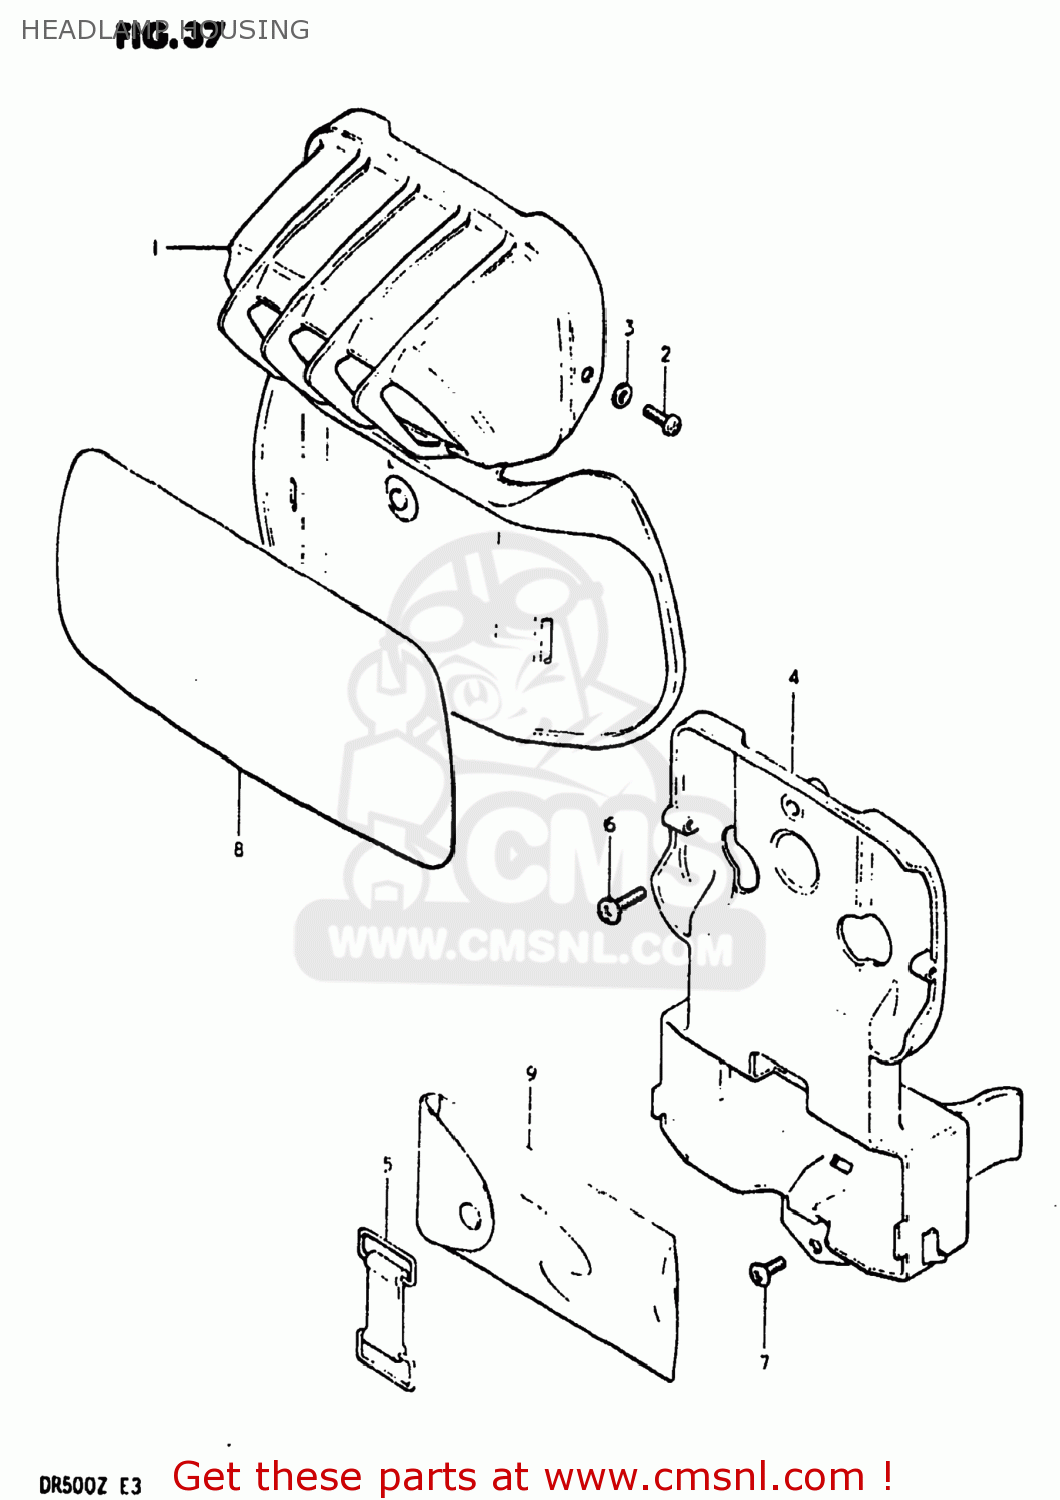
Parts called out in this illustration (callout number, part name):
1	HOUSING,HEADLAMP
2	TAPPING SCREW
3	WASHER
4	HOLDER,TOOL
5	BAND
6	SCREW
7	SCREW
8	EMBLEM,FRONT NUMBER PLATE
9	TOOL SET
